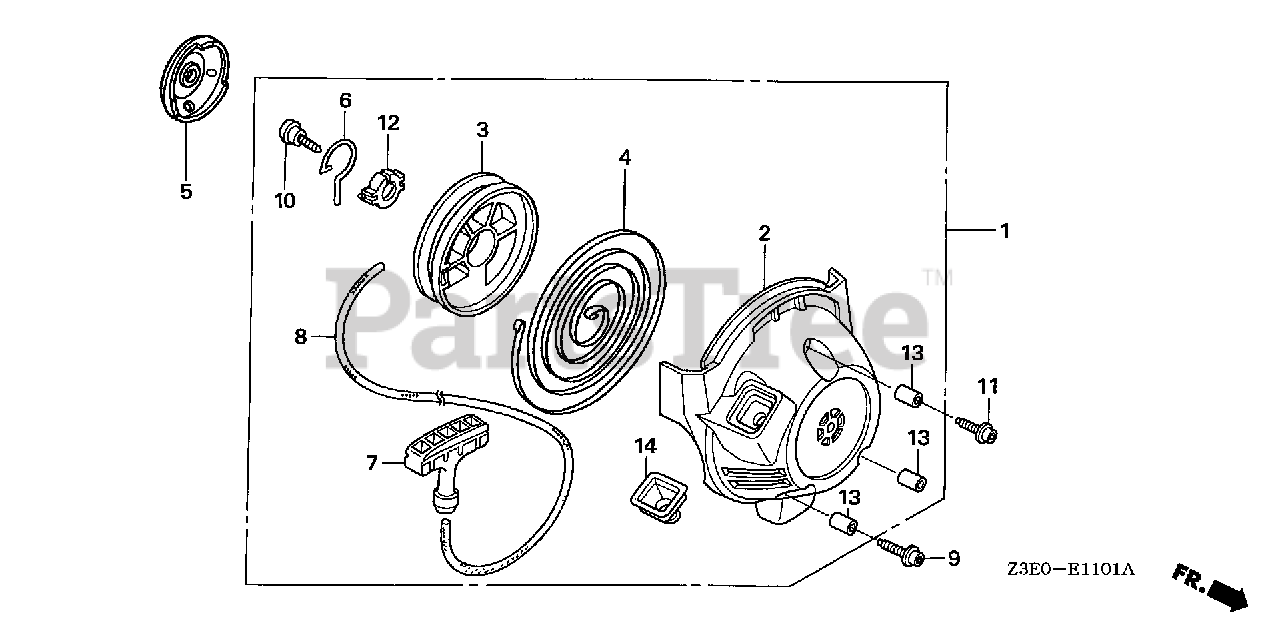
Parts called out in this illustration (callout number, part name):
1	STARTER ASSY., RECOIL *T91* (HUSQVARNA ONLY) (HUSQVARNA ORANGE)
2	CASE, RECOIL STARTER *T91* (HUSQVARNA ONLY) (HUSQVARNA ORANGE)
3	REEL, RECOIL STARTER
4	SPRING, RECOIL STARTER
5	PULLEY, RECOIL STARTER
7	KNOB, RECOIL STARTER
8	ROPE, RECOIL STARTER (#3.5X40")
9	BOLT, SOCKET (5X20)
10	SCREW, SETTING
11	BOLT, SOCKET (5X16)
13	COLLAR A, HEAD COVER
14	GUIDE, ROPE
